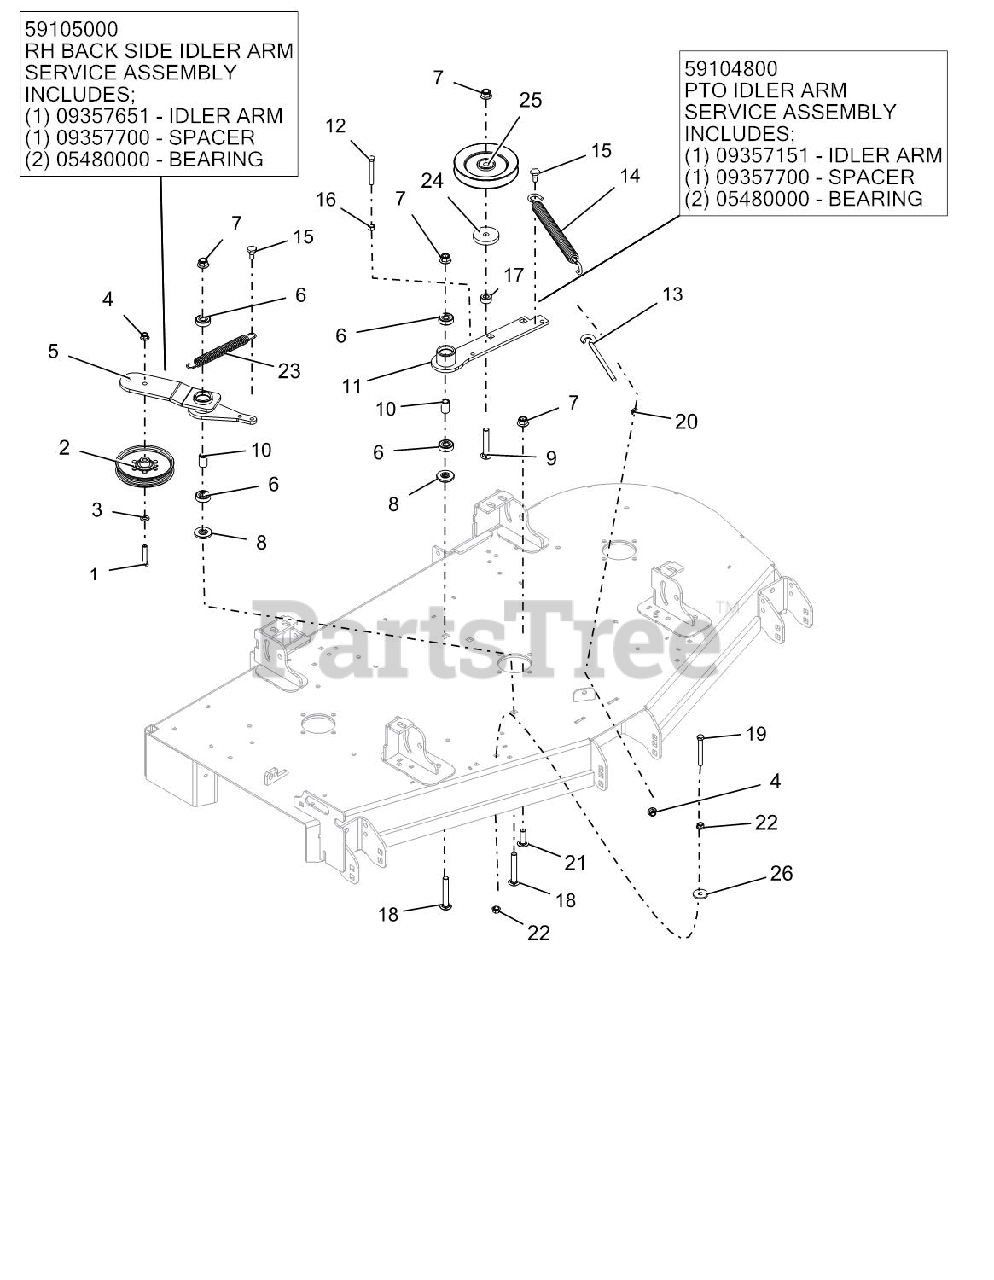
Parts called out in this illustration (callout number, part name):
1	BLT-HEX .38-16X2.00 GR5 YWZC
2	PULLEY, FLAT IDLER
3	WSHR-FL-STL.406X.812X.065 YWZ
4	NUT-LK-NYL-FLG .38-16 YWZC
5	BRG-BALL .50X1.38X.438 SEALED
5	SPACER .510 X .75 X 1.1485
5	DECK RH IDLER ARM WMT - BLK
5	RH BACKSIDE IDLER ARM ASSEMBLY
6	BRG-BALL .500X1.38X.437
7	NUT-LK-NYL-FLG .50-13 YWZC
8	SPACER, IDLER ARM
9	BLT-RDHDSQNK .50-13X3.00 G5YZ
10	SPACER .510 X .75 X 1.1485
11	BRG-BALL .50X1.38X.438 SEALED
11	SPACER .510 X .75 X 1.1485
11	DECK PTO IDLER ARM WMT - BLK
11	PTO IDLER ARM ASSEMBLY
12	BLT-HEX .38-16X2.75 GR5 YWZC
13	BOLT, .38-16X6.00 .62 DIA EYE
14	SPRING, EXTENSION
15	BLT,SHLDR EP .38-16X.30 HEX YZ
16	NUT-HEX .38-16 YWZC
17	BSHG, SPCR .502X.997X.50 PM
18	BLT,RDHDSQSHNK.50-13X3.25 G5YZ
19	BLT-HEX .38-16X3.00 GR5 YWZC
20	NUT-HEX-JAM .375-16 YWZC
21	BLT-RDHDSHSQNKFT.50-13X1.50 G5
22	NUT-SPNLK-FLG .375-16 YWZC
23	SPRING, EXTENSION
24	CAP, IDLER BEARING SEALING
25	SHV, .50"ID X 6.00"OD V-IDLER
26	WSHR-FL-STL .406X1.375X.135 YZ
